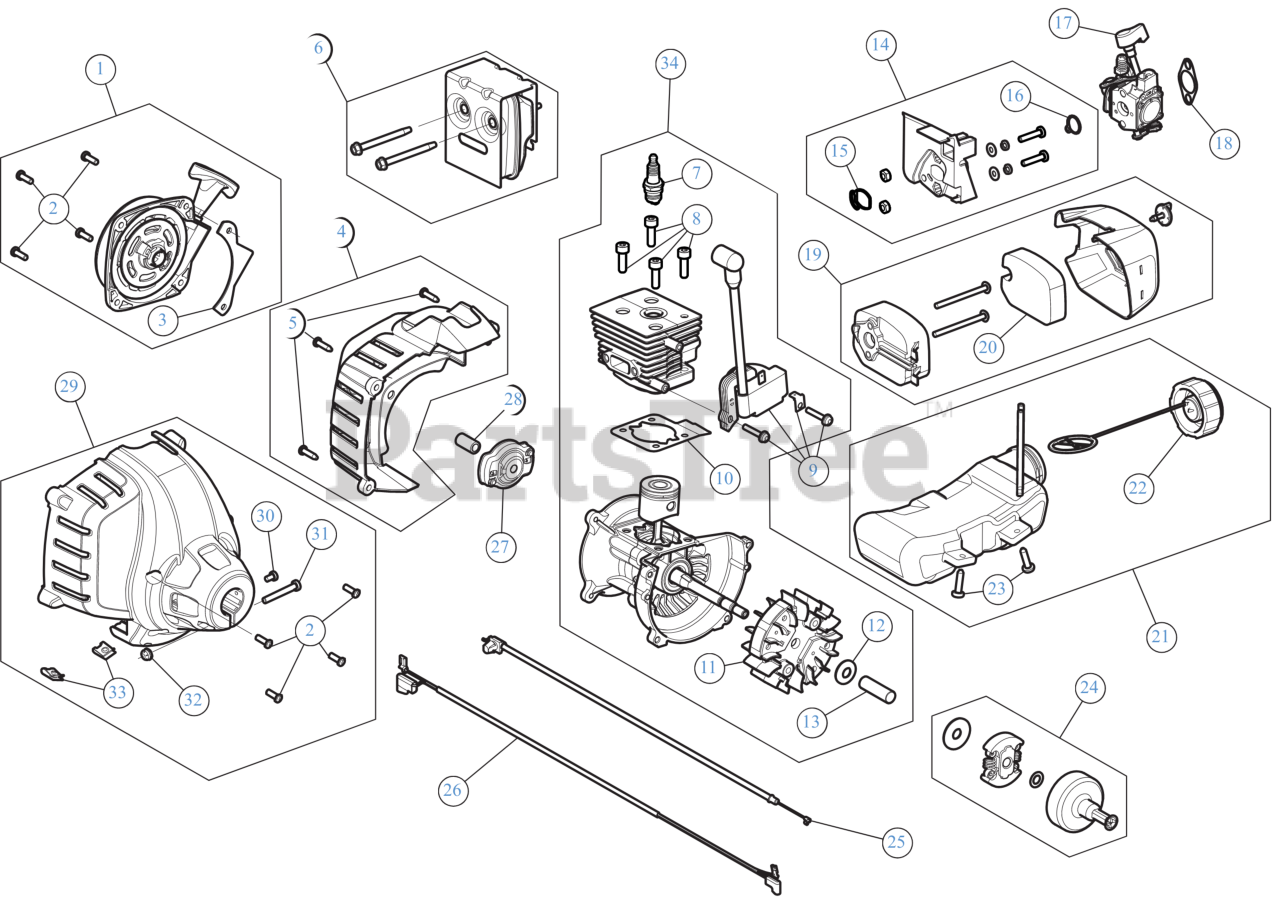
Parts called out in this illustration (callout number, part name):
1	STARTER ASSEMBLY RR
2	SCREW:10-32X.562:#8P
3	STARTER GUARD
4	REAR ENGINE COVER
5	SCREW, #8-16X.750 PH
6	MUFFLER ASSEMBLY
7	SPARK PLUG
8	SCREW 1/4 x 20 x .8125
10	GASKET CYL
11	FLYWHEEL ASSEMBLY 27CC
12	BELL WASHER
14	INTAKE ASSEMBLY
17	CARBURETOR (WALBRO)
18	GASKET CARB
19	AIRCLEANER ASSEMBLY
20	AIR FILTER
21	FUEL TANK ASSEMBLY
23	SCREW:10-6 x .75
24	SMALL CLUTCH ASSEMBLY W/SMALL DRUM
25	THROTTLE CABLE
26	LEAD WIRES
27	PAWL ASSEMBLY AC5
28	ELECTRIC START ADP
29	CLUTCH COVER ASSEMBLY
30	SCREW, 8-32 x .312 P
31	SCREW
33	NUT, TINNERMAN U-T
34	SHORT BLOCK ASSEMBLY
